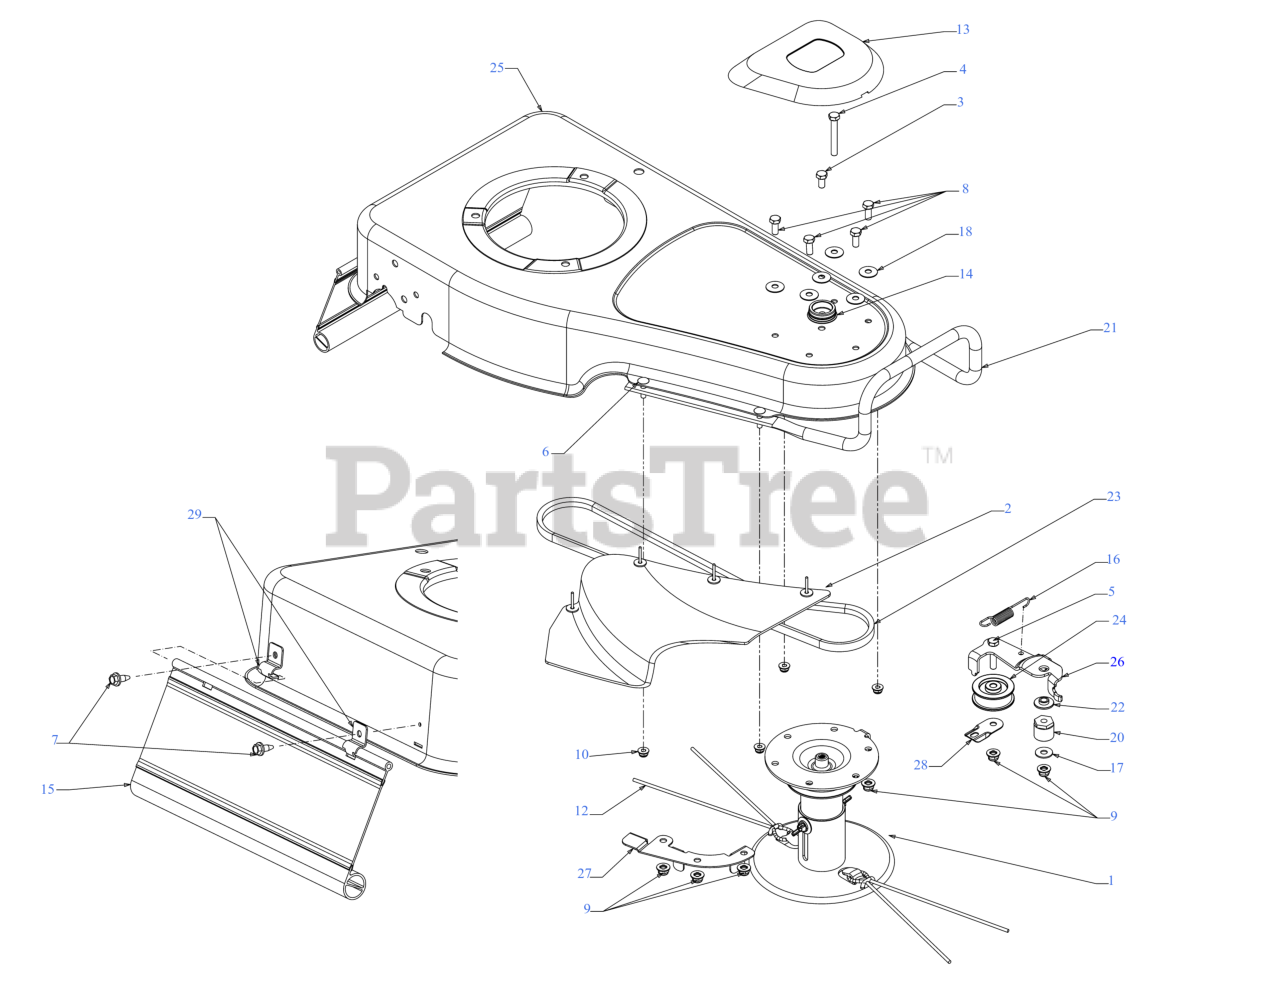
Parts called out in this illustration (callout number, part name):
1	SPINDLE ASSEMBLY
2	22" DEFELECTOR ASSEMBLY
3	HEX SCREW 5/16-24 x .62
4	HEX SCREW 5/16-18 x 2.25 GR5
5	SCREW 5/16-18 x 1.5 LG
6	SCREW 1/4-20 x 1 GR5
7	SCREW 1/4-20X.625
8	SCREW 5/16-18 x .75 GR5
9	FLANGE LOCK NUT 5/16-18
10	FLANGE LOCK NUT
12	TRIMMER LINE: 10 P
13	COVER TRIM
14	COVER TRIM RETAINER
15	TRAILSHIELD
16	EXTENSION SPRING .500 OD x 3.375
17	FLAT WASHER
18	BELL WASHER
21	FRONT BUMPER
22	IDLER SPACER
23	V-BELT 4L x 44.6"
24	IDLER PULLEY
25	STRING TRIMMER BASE
26	IDLER BRACKET
29	TRAILSHIELD HINGE CLIP
